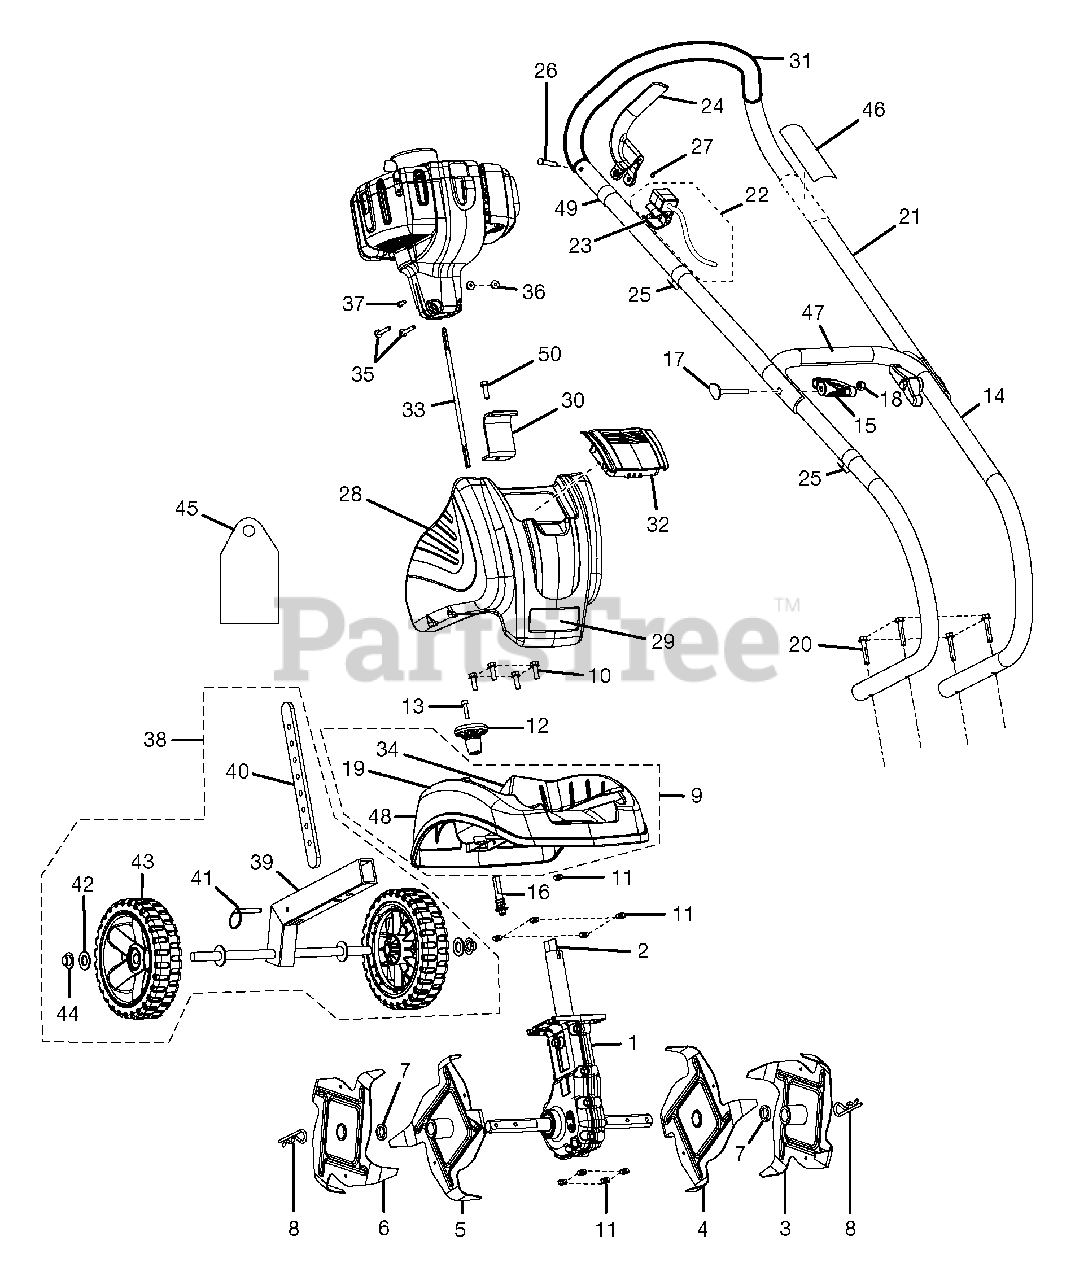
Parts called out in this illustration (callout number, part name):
1	GEAR BOX ASSEMBLY WITH TUBE
2	LINER - DRIVE TUBE
3	TINE A, OUTER RIGHT
4	TINE B, INNER RIGHT
5	TINE C, INNER LEFT
6	TINE D, OUTER LEFT
7	FELT WASHER
8	CLEVIS CLIP
9	TINE SHIELD ASSEMBLY
10	BOLT (1/4-20 X 1 in.)
11	LOCK NUT (1/4-20)
12	RECEIVER RETAINER KNOB
13	SCREW (M5 X 16 mm PAN HD.)
14	LOWER HANDLE ASSEMBLY
15	KNOB (1/4-20)
16	RECEIVER RETAINER ASSEMBLY
17	CARRIAGE BOLT (1/4-20 X 2-1/4 in.)
18	ACORN NUT
19	WARNING LABEL, FOOT
20	HANDLE BOLT (1/4-20 X 1.53 in.)
21	UPPER HANDLE ASSEMBLY
22	THROTTLE CABLE ASSEMBLY
25	PLASTIC CLIP
26	CLEVIS PIN
27	RETAINING RING
28	TANK - BALLAST ASSEMBLY
29	LOGO LABEL
30	MOUNTING BRACKET
32	BALLAST TANK LID
33	FLEXIBLE DRIVE SHAFT
34	WHEEL ACCESSORY LABEL
35	BOLT (10-24 X 1-1/4 in.)
36	NUT (10-24)
37	SCREW (8-16 X 1/2 in.)
38	WHEEL/DRAG STAKE ASSEMBLY
39	FRAME ASSEMBLY
40	DRAG STAKE
41	QUICK RELEASE PIN
42	FLAT WASHER
43	WHEEL ASSEMBLY (7 in. DIA.)
44	PUSH CAP NUT (FITS 1/2 in.)
45	WARNING HANG TAG
46	BOOM WARNING LABEL
47	STARTING LABEL
48	WARNING LABEL
49	PLASTIC ROPE CLIP
50	BOLT (1/4-20 x 5/8 in.)
